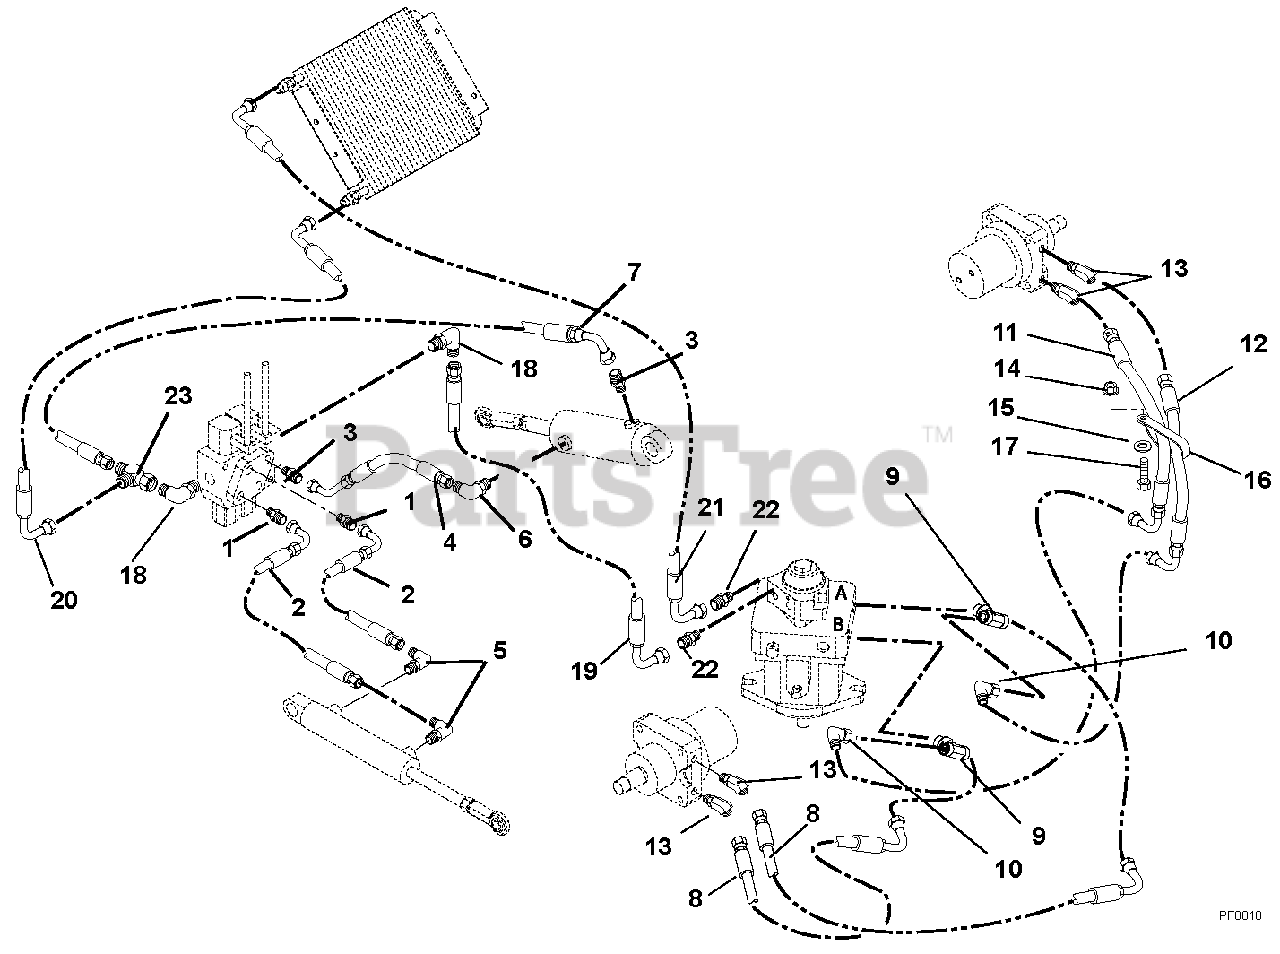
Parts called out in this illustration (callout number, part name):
14	1
15	1
17	1
